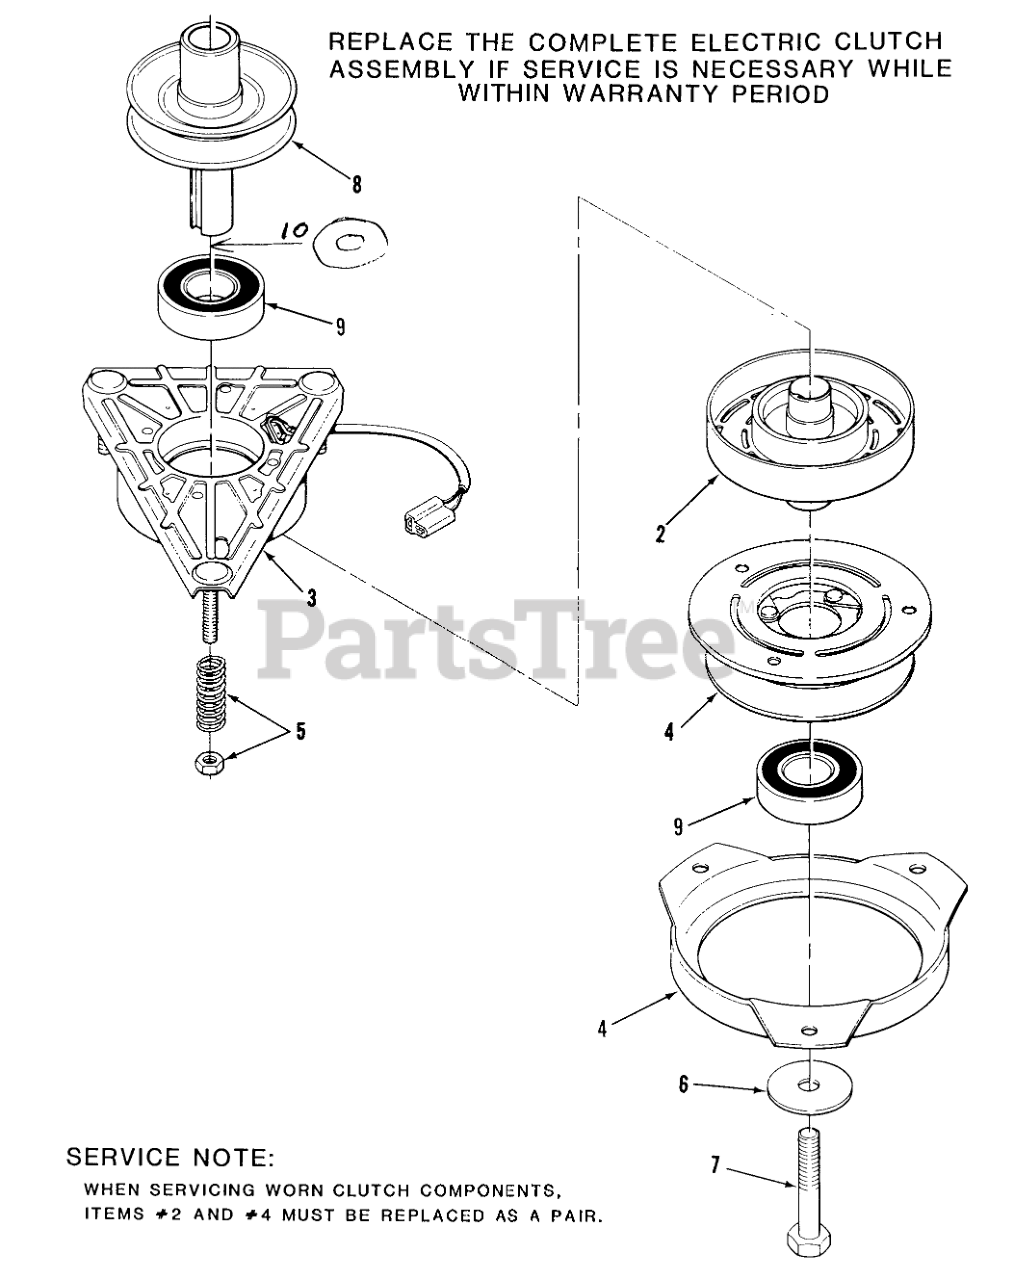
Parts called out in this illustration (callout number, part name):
2	Rotor Assy
3	Field Assy (includes one of item 9)
4	Armature and Pulley Assy (includes one of item 9 and Brake Plate)
5	4XC6898/4XF6899 CLU
6	Washer
7	Bolt M10x1.50 x 120. (212-5, 212-H)
8	33054A GIL/938 TRAI
9	Ball Bearing
10	Washer
